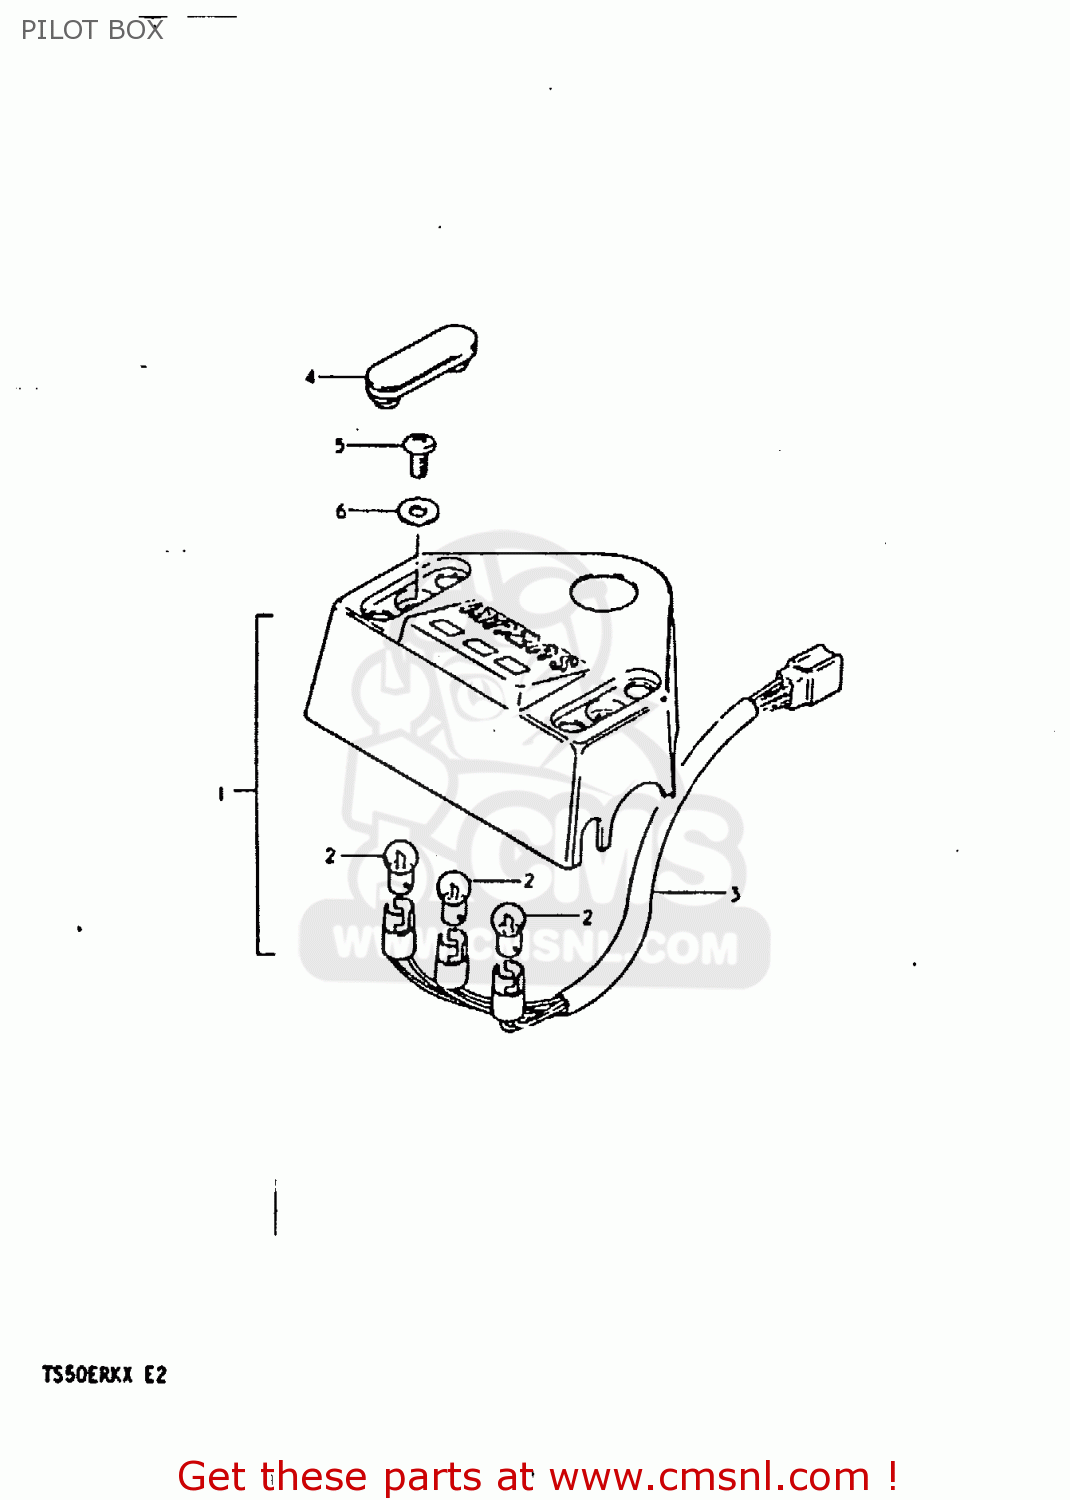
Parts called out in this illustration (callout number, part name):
1	PILOT BOX ASSY
2	BULB(6V/3W)
3	SOCKET
4	CAP,PILOT BOX BOLT
5	SCREW 6X12
6	WASHER
